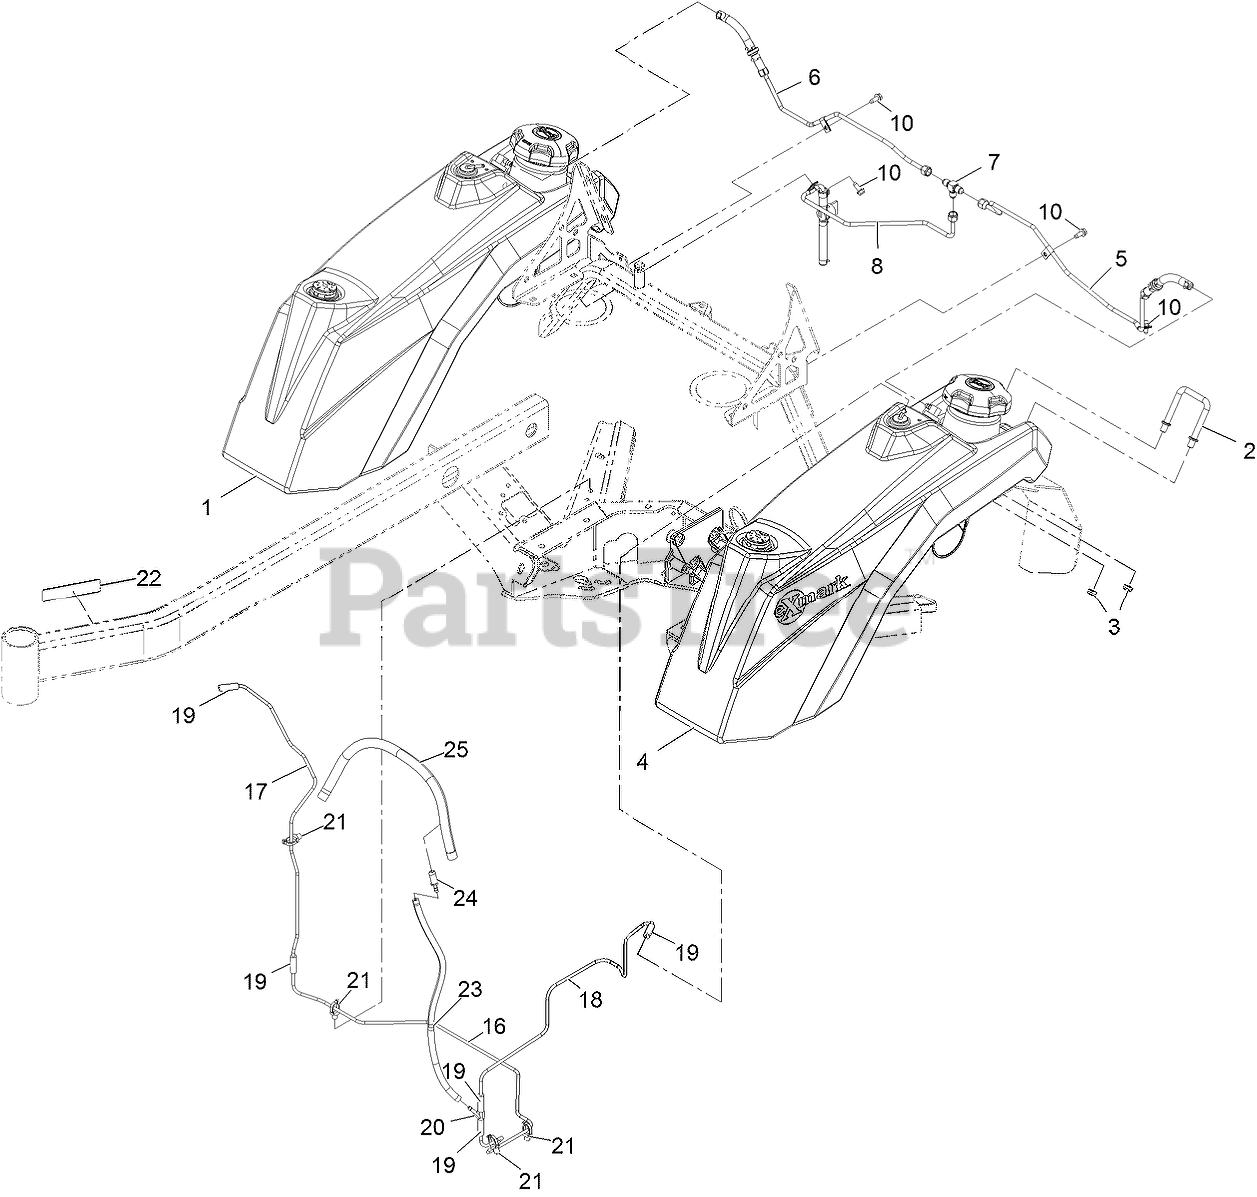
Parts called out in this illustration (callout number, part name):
1	ASM, Rt Fuel Tank
2	Clamp, Tank
4	ASM, Lt Fuel Tank
5	ASM, Left Fuel Line
6	ASM, Right Fuel Line
7	Fitting, 2603-4-4-4
8	ASM, Kaw Fuel Line
10	SCREW-HWH
16	Line, Vent, Main
17	Line, Vent, Right
18	Line, Vent, Left
19	HOSE-FUEL
20	Fitting, 3/16" Y
21	CLIP-TIE
22	DECAL-ARRESTOR, SPARK
23	Hose, Vent
24	FITTING-STRAIGHT
25	HOSE-FUEL
